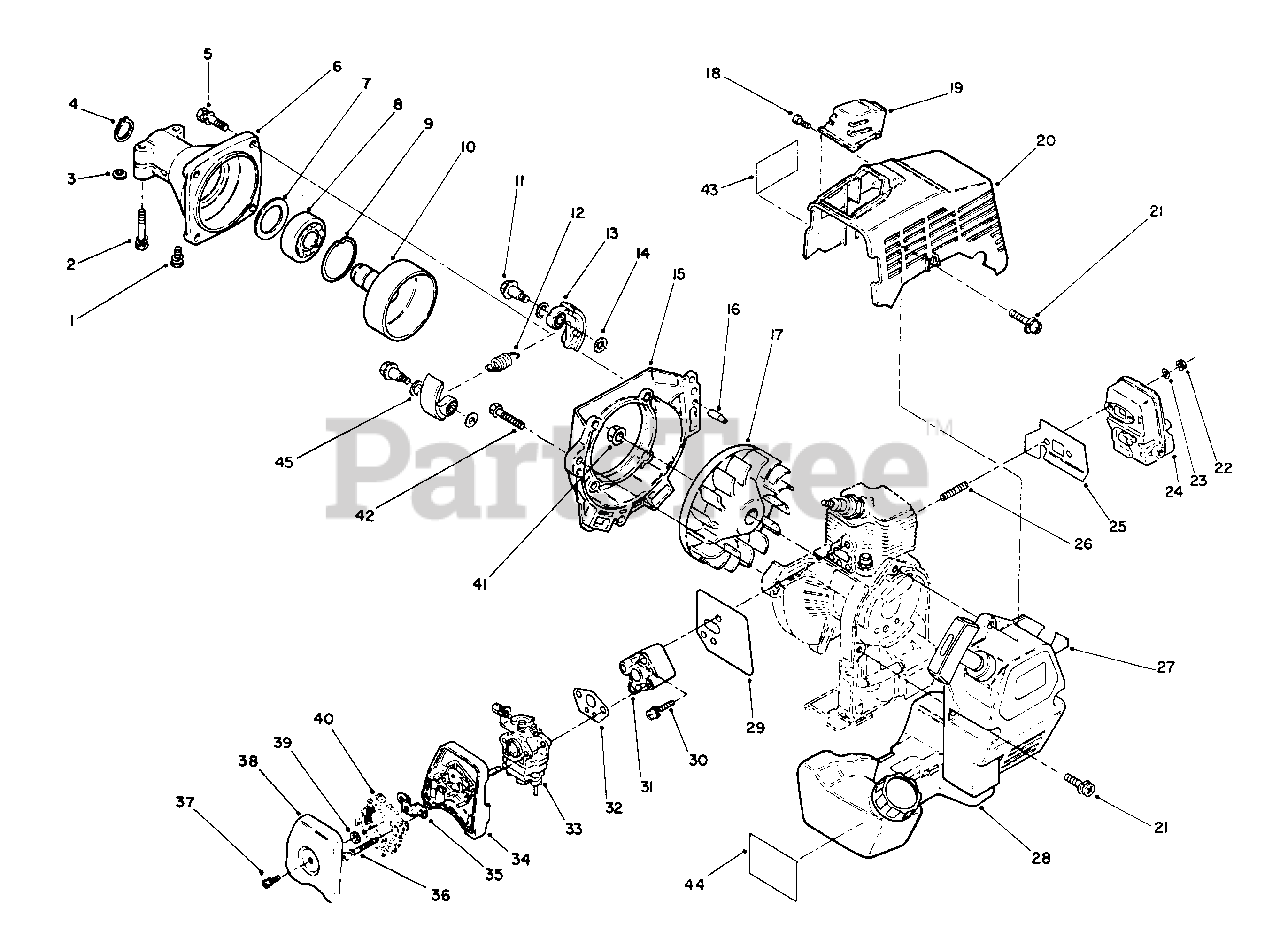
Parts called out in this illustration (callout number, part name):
1	Screw/Washer
2	Bolt/Washer
4	Ring-Retaining
5	Bolt/Washer
6	Case-Clutch
8	Bearing-Ball
9	Ring-Retaining
10	Drum-Clutch
11	Bolt-Clutch
12	Spring
13	Flyweight
15	Case-Fan
16	Pin-Dowel
17	Fan
19	Guard-Spark Plug
20	Cover-Engine
21	Screw/Washer
22	Nut-Flange Lock
24	Muffler Assembly
25	Gasket-Muffler
27	Recoil Assembly
28	Tank Assembly-Fuel
29	Gasket-Insulator
30	Screw/Washer
31	Insulator
32	Gasket-Carburetor
33	Carburetor Assembly
34	Case-Air Cleaner
36	Screw/Washer
37	Screw/Washer
38	Cover-Air Cleaner
40	Element-Air Cleaner
41	Nut-Conical
42	Screw-Pan Hd.
43	Decal-Hot
44	Decal-Fuel Mix
45	Washer-Wave
